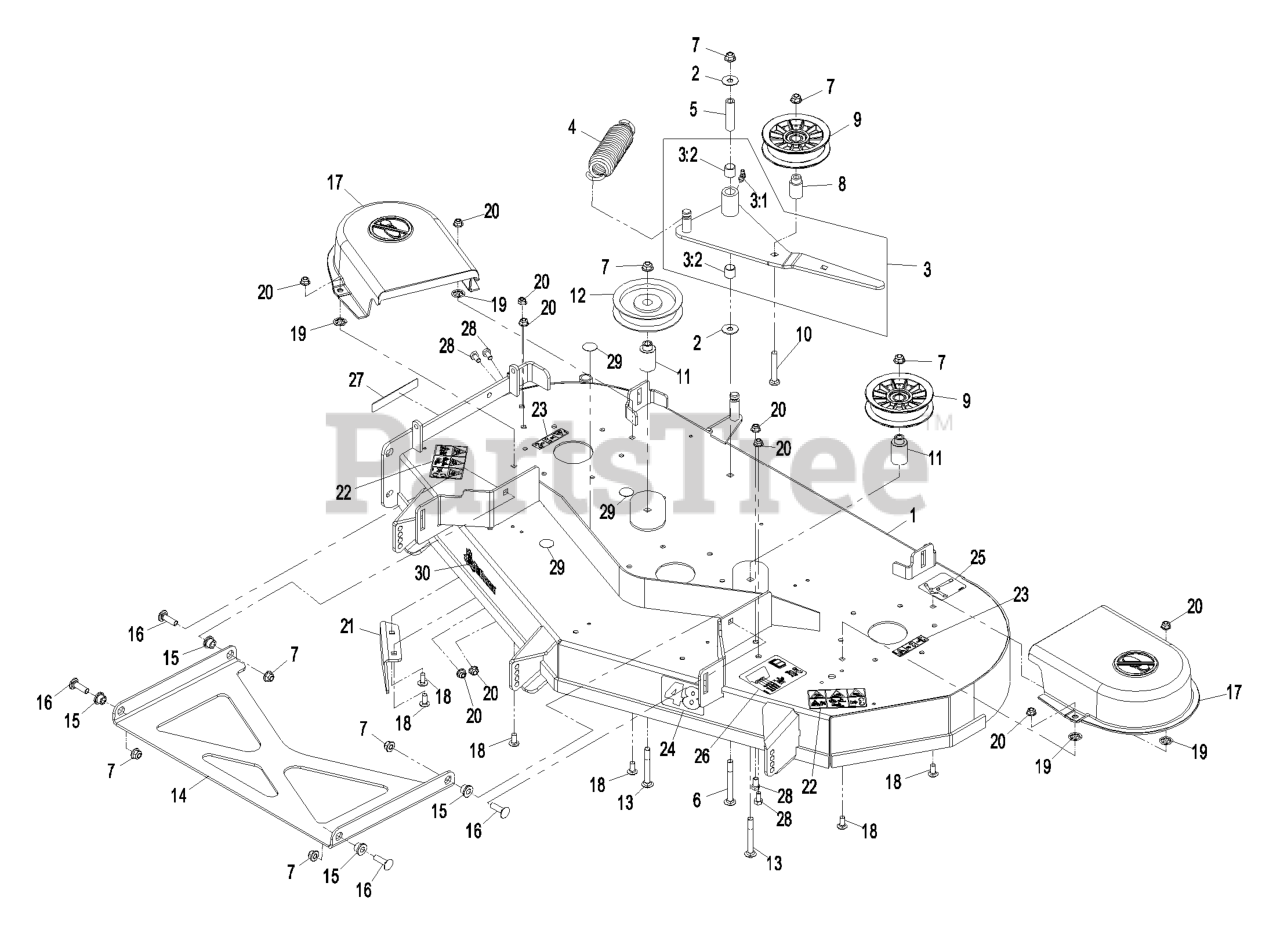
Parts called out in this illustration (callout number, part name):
1	48 INCH DECK ASM
3	IDLER ARM ASM
3:1	FITTING-GREASE, 90 DEG
3:2	SLEEVE-BEARING
5	BUSHING-PIVOT, IDLER
6	SCREW-CARR
7	NUT-HF, NI
8	BUSHING-IDLER
9	SHEAVE AND BEARING ASM
10	SCREW-CARR
11	BUSHING-IDLER
13	BOLT-CARRIAGE
14	STRUT-DECK
15	BUSHING-FLANGED
16	BOLT-CARR
17	SHIELD-BELT
18	SCREW-CARR
19	RING-RETAINING, BOLT
20	NUT-HF, NI
21	BAFFLE-DISCHARGE
22	DECAL-DANGER
23	DECAL-WARNING, BELT SHIEL
24	DECAL,DECK 48
25	DECAL-ROUTING, BELT
26	DECAL-ROLLER, ANTI-SCALP
27	DECAL-DANGER
28	SCREW-HH
29	DECAL-HOLE COVER
